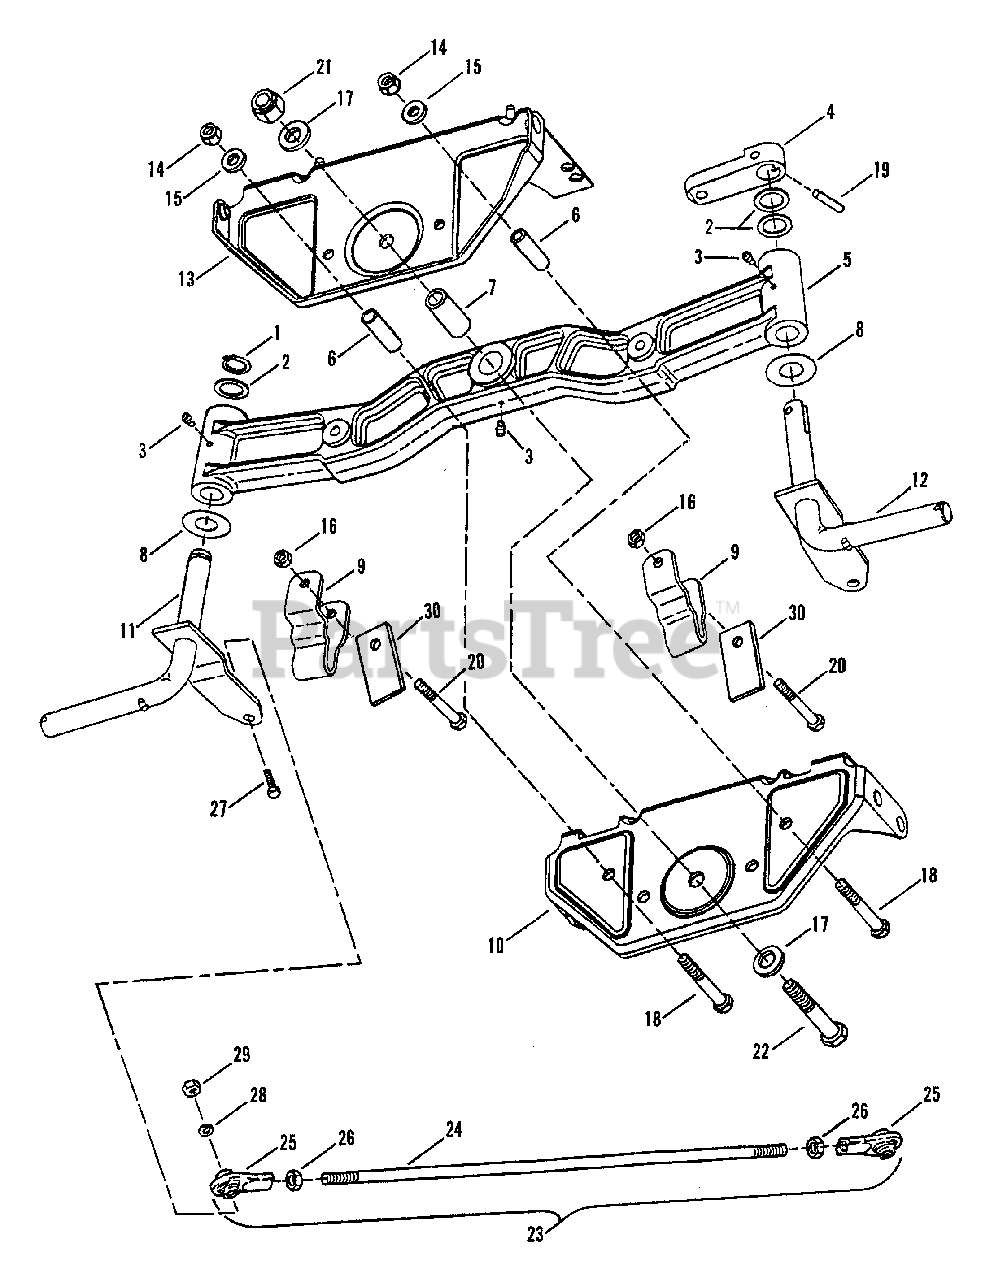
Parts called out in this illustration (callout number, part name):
1	RING, 5/8 External Retaining
2	WASHER, 49/64 x 1-1/8 x 1/16" Flat
3	FITTING, 3/16 Lube
4	ARM, Steering
5	AXLE, Cast
6	SPACER, 25/64 x 1/2 x 1-13/16"
7	SPACER, Center
8	WASHER, Thrust
9	BRACKET, Deck Hanger
10	BRACKET, Cast Axle (Rear)
11	WELDMENT, Right Hand Spindle Wheel (Short)
12	WELDMENT, Left Hand Spindle Wheel (Short)
13	* BRACKET, Cast Axle Front
14	NUT, 3/8-16 Hex Nyloc
15	WASHER, 3/8 x 5/64" Flat
16	NUT, 5/16-18 Hex Center Lock
17	WASHER, 1/2 x 3/32" Flat
18	SCREW, 3/8-16 x 2-3/4" Hex Head Cap, Grade 2
19	PIN, 1/4 x 1-1/4" Roll
20	SCREW, 5/16-18 x 2-3/4" Hex Head Cap, Grade 5
21	NUT, 1/2-13 Hex Nyloc
22	SCREW, 1/2-13 x 3" Hex Head Cap Grade 5
23	ASSEMBLY, Tie Rod
24	ROD, Steering Connector
25	BALL JOINT, 3/8-24 thread
26	NUT, 3/8-24 Hex Jam
27	SCREW, 3/8-16 x 1-1/2" Hex Head Cap, Grade 5
28	WASHER, 3/8 Split Lock
29	NUT, 3/8-16 Hex, Grade 5
30	SPACER, Steering Stop
